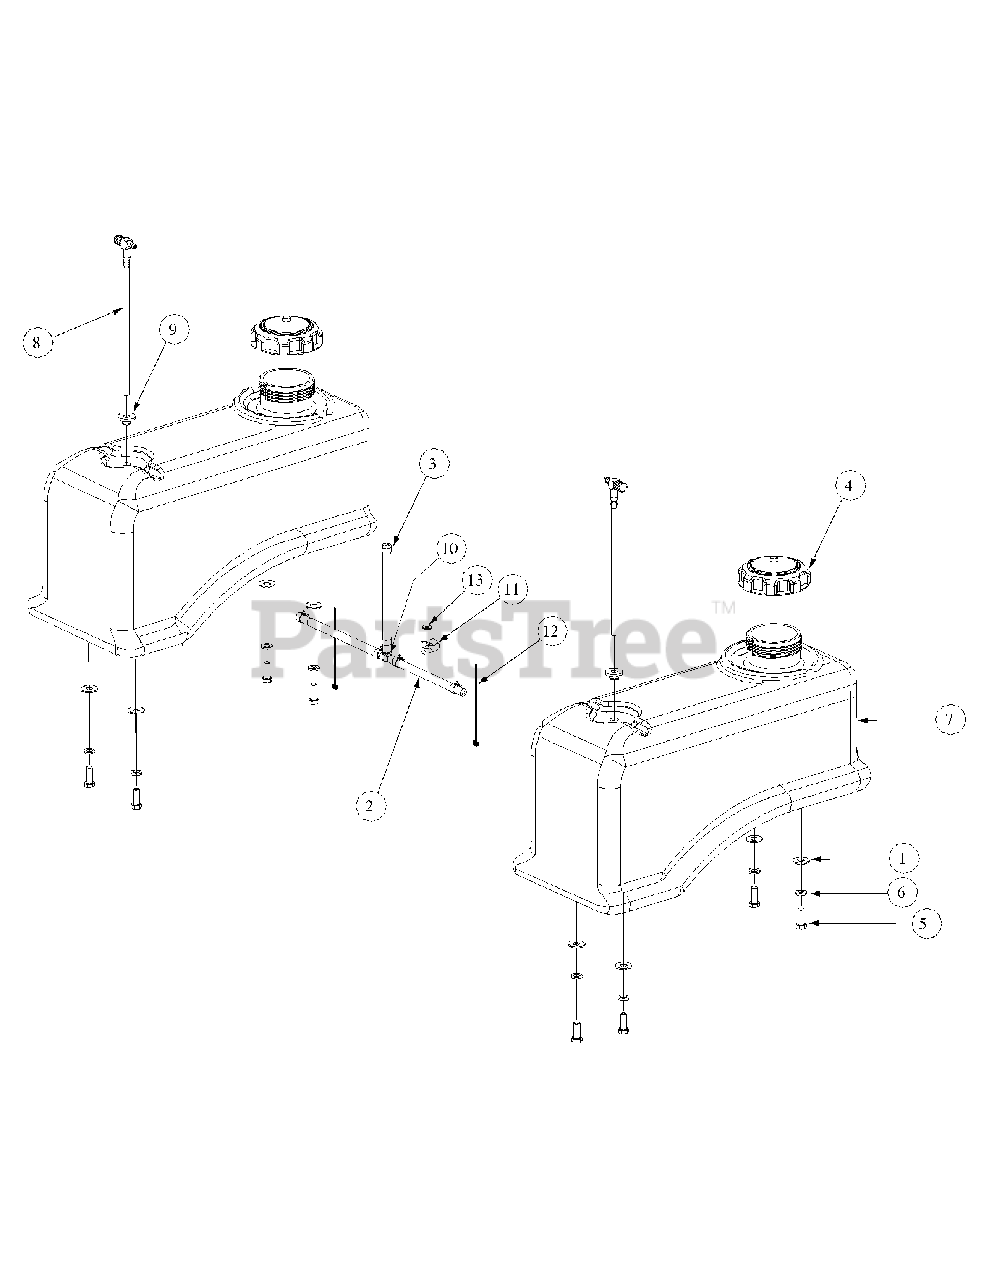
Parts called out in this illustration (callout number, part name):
1	Flat Washer, .406 ID, 1.0 OD, .105
2	Hose, 1/4" Fuel Line 79.5"
3	Clamp, Union
4	Fuel Cap, 3.5
5	Hex, Cap Screw, 3/8-16, .88
6	Lock Washer, 3/8
7	Fuel Tank
8	Fuel Fitting
9	Grommet, Fuel Tank
10	Tee Fitting, Fuel
11	Clamp, 1/2 Tubing
12	Cable Tie
13	Flat Washer, 1.4 x .630 x .0515
